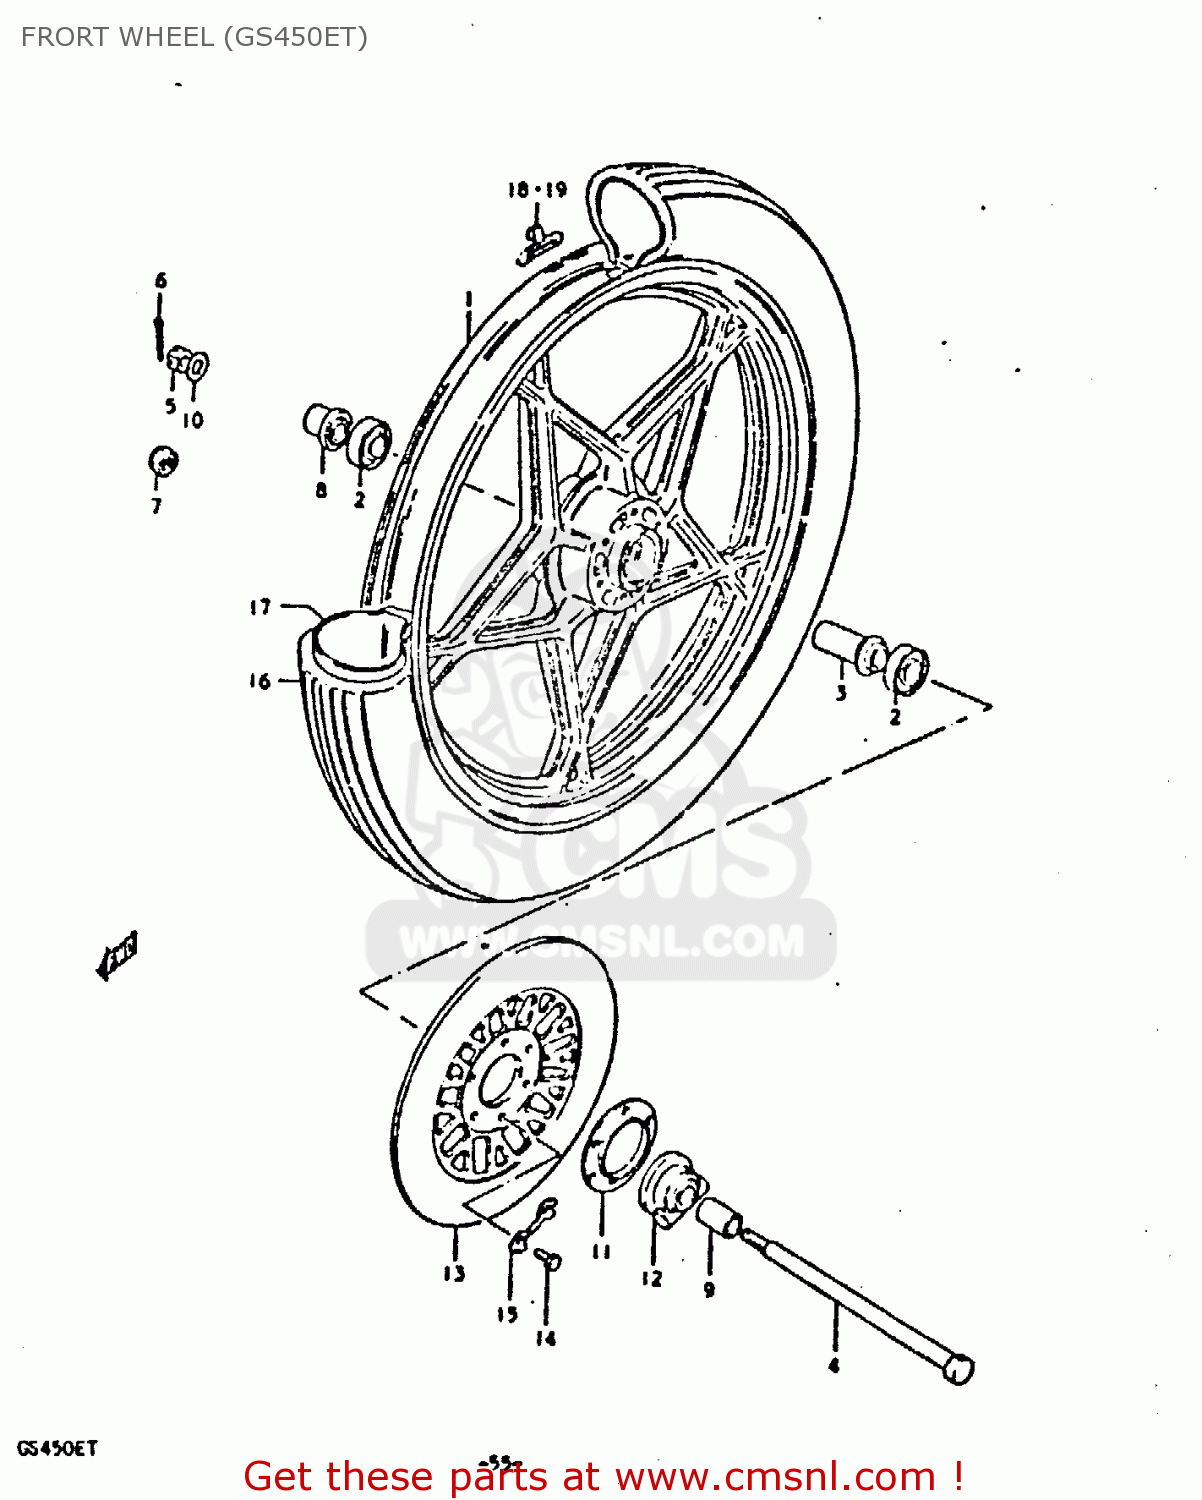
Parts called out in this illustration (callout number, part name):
1	WHEEL (DARK GRAY)
2	BEARING
3	SPACER(15.3X21.7X63)
4	AXLE,FRONT
5	NUT 12MM
6	COTTER PIN
8	SPACER,FR HUB BEARING,R
9	SPACER(15X22X30)
10	WASHER
11	DUST SEAL,SPEEDOMETER GEAR BOX
12	BOX ASSY,SPEEDOMETER GEAR
13	DISC,FR BRAKE
14	BOLT(8X25)
15	WASHER
16	TIRE,FRONT
17	TUBE,INNER
18	BALANCER,WHEEL
19	BALANCER,WHEEL
